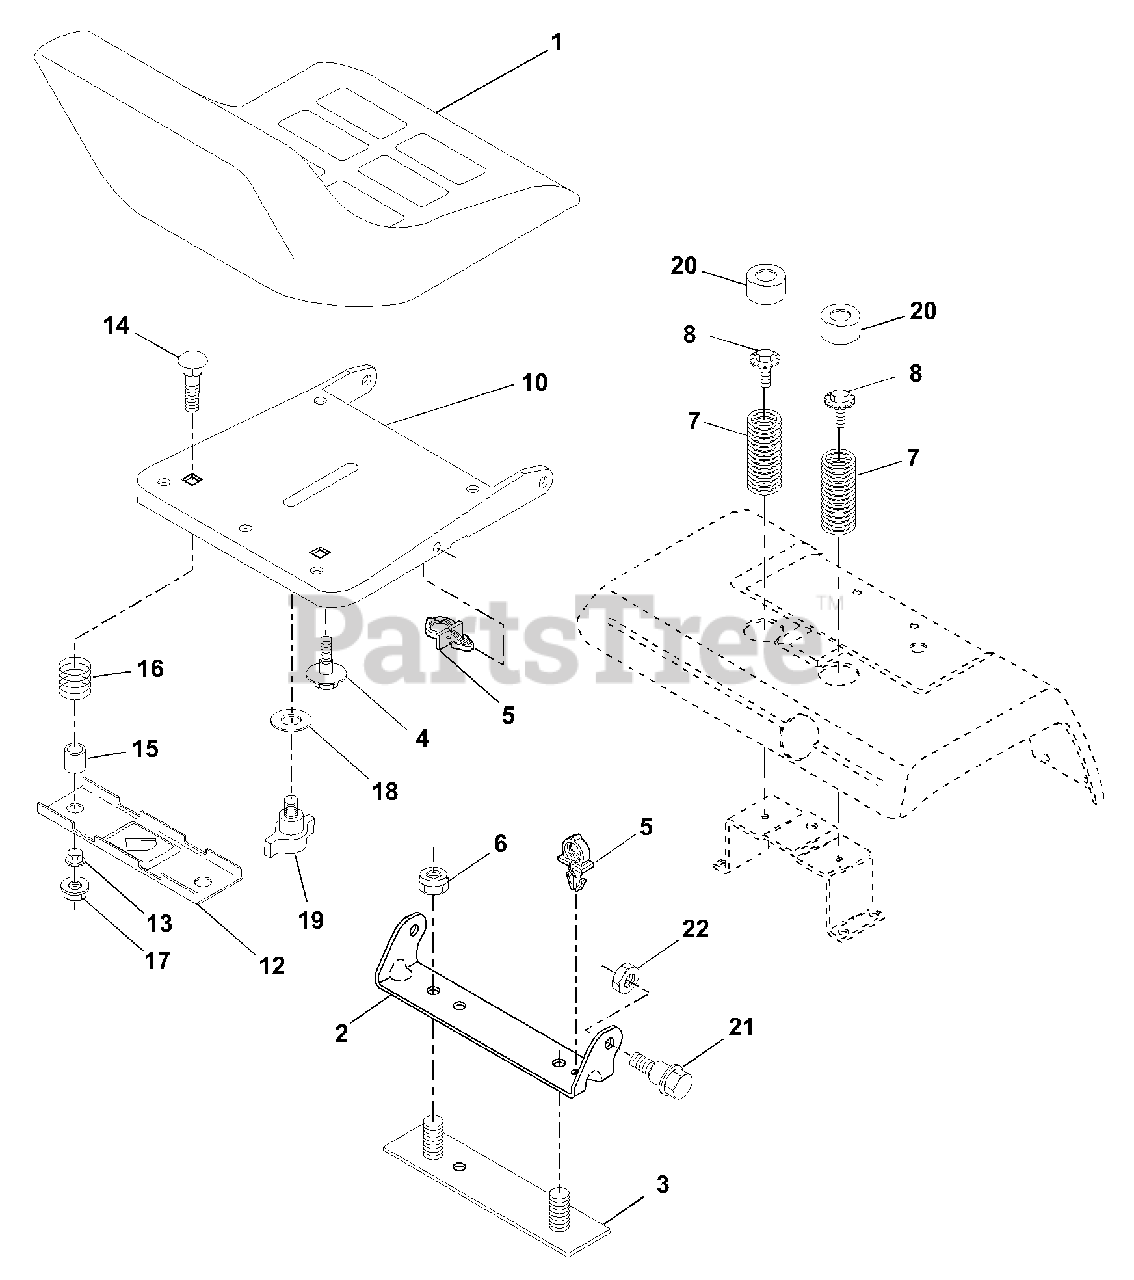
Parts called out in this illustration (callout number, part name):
1	Seat
2	Bracket, Pivot Seat
3	Strap, Fender
4	Bolt, Shoulder 5/16-18 X .62
5	Clip, Push In Hinged
6	Nut, Crownlock 3/8-16
7	Spring, Seat Cprsn
8	Bolt 5/16-18 UNC X 3/4
10	Pan, Seat
12	Bracket, Mounting Switch
13	Bushing, Snap
14	Bolt, Carriage 1/4-20 X 1-1/2
15	Spacer, Split
16	Spring, Cprsn
17	Nut, Lock 1/4 Lge Flg Gr. 5
18	Washer 17/32 X 1-3/16 X 12 Ga.
19	Knob, Seat
20	Cap, Spring Seat
21	Bolt, Shoulder 5/16-18
22	Nut, Crownlock 5/16-18
